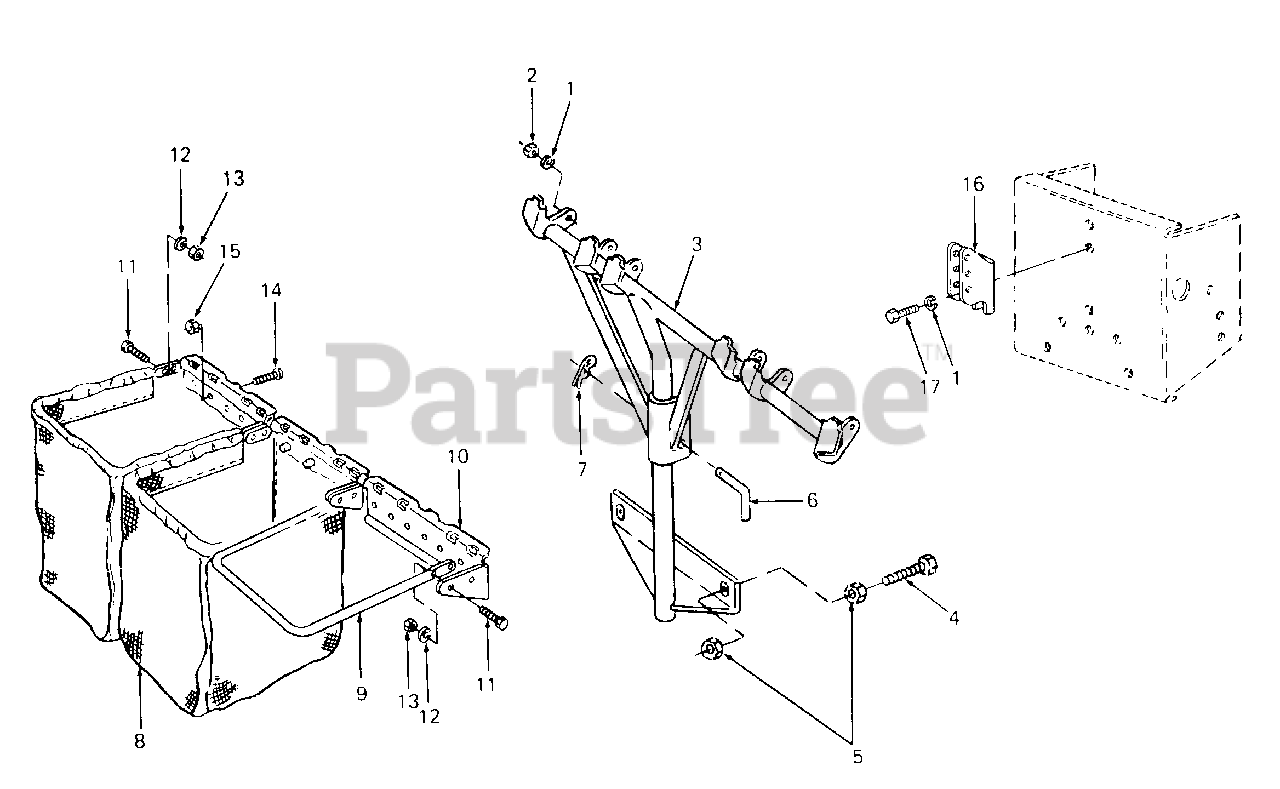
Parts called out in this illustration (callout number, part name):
1	Washer, Lock, 3/8
2	Nut, Hex, 3/8-16
5	Nut, Hex Jam, 3/8-16 GR5
6	Pin, Right Angle Clevis
7	Pin, Internal Cotter, 5/8 Dia
8	Bag, Grass Catcher
9	Frame, Catcher Bag
11	Screw, Hex Cap, 1/4-28 X .75 Lg
12	Washer, Lock, 1/4
13	Nut, Hex, 1/4-28
14	Screw, Truss Mach, #10-24 X .38 Lg
15	Nut, Hex Sems, #10-24
17	Screw,Hex Cap.3/8-16 X .88 Lg GR5
